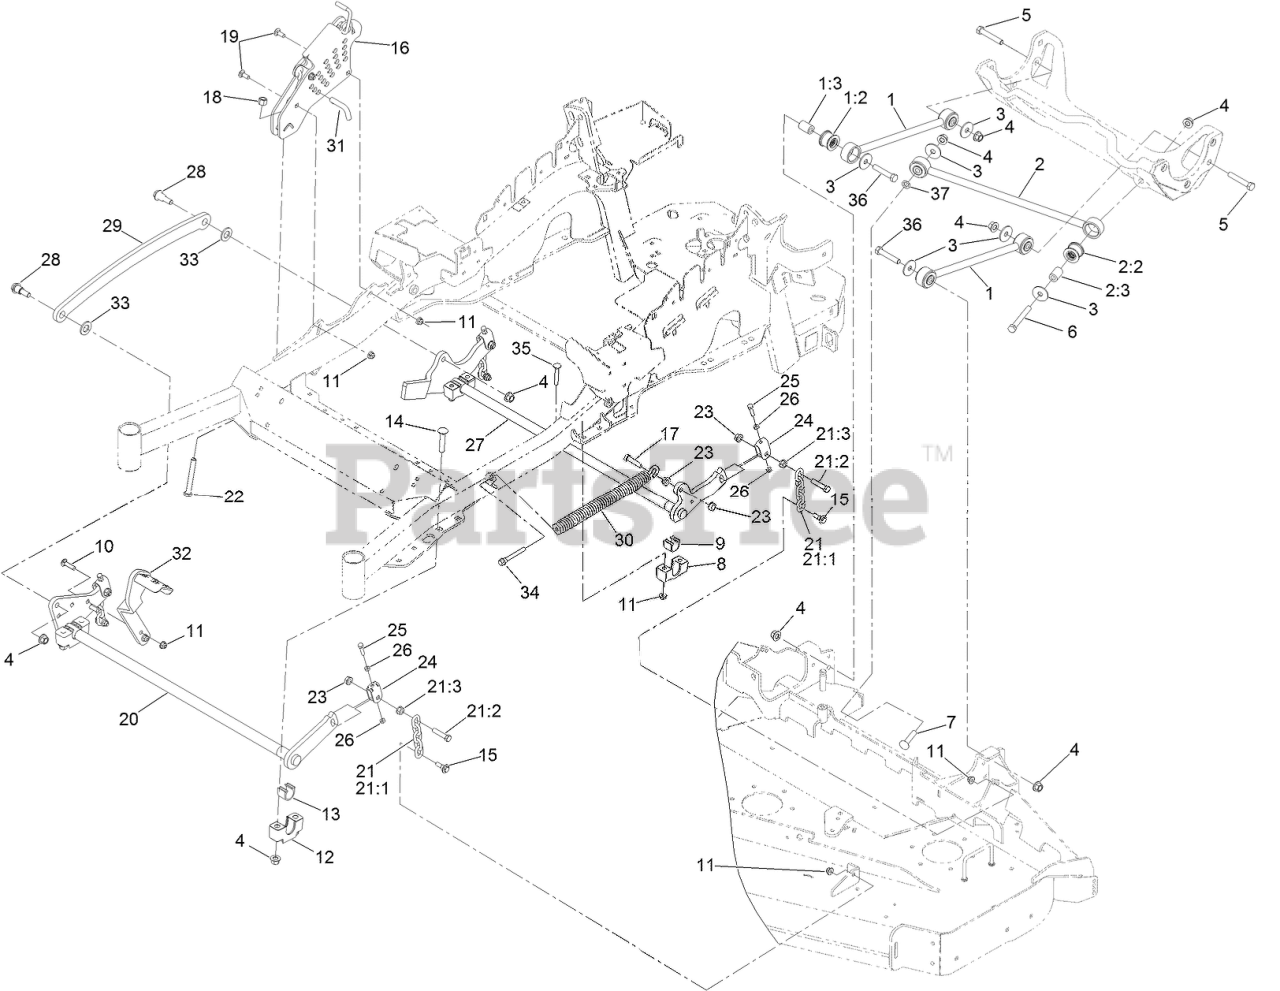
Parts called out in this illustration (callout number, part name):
1	DECK STRUT ASM
1:2	BUSHING-SUSPENSION, RUBBER
2	PANHARD ROD ASM
2:2	BUSHING-SUSPENSION, RUBBER
3	WASHER-THRUST
4	Nut-Lock 1/2-13
5	SCREW-HH
6	SCREW-HH
7	SCREW-CARR
8	SUPPORT-CROSS SHAFT, BEARING REAR
9	BEARING-CROSS SHAFT, REAR
10	SCREW-CARR
11	NUT-HF, NI
12	SUPPORT-CROSS SHAFT, BEARING
13	BEARING-CROSS SHAFT, FRON
14	Bolt-Carriage 1/2-13 X 2 1/2 Spl Neck
15	SCREW-SHOULDER, HHF
16	HOC ASM
17	SCREW-HH
18	NUT-LOCK, NI
19	BOLT-CARR
20	DECKLIFT-FRONT
21	DECK LIFT CHAIN ASM
21:1	CHAIN-LIFT, DECK
21:2	SCREW-HH
22	BOLT-TAP
24	YOKE-ADJUST, DECK
25	SCREW-HH
26	NUT-JAM
27	LIFT-DECK, REAR
28	SCREW-SHOULDER, HHF 1/2-13 X 1.12
29	LINK-LIFT, DECK
30	SPRING-EXTENSION
31	PIN-HOC
32	LEVER-FOOT
33	WASHER-FLAT
34	BOLT-SHOULDER
35	Bolt-Carriage 3/8-16 X 2 1/4
36	SCREW-HH
37	NUT-PUSH
